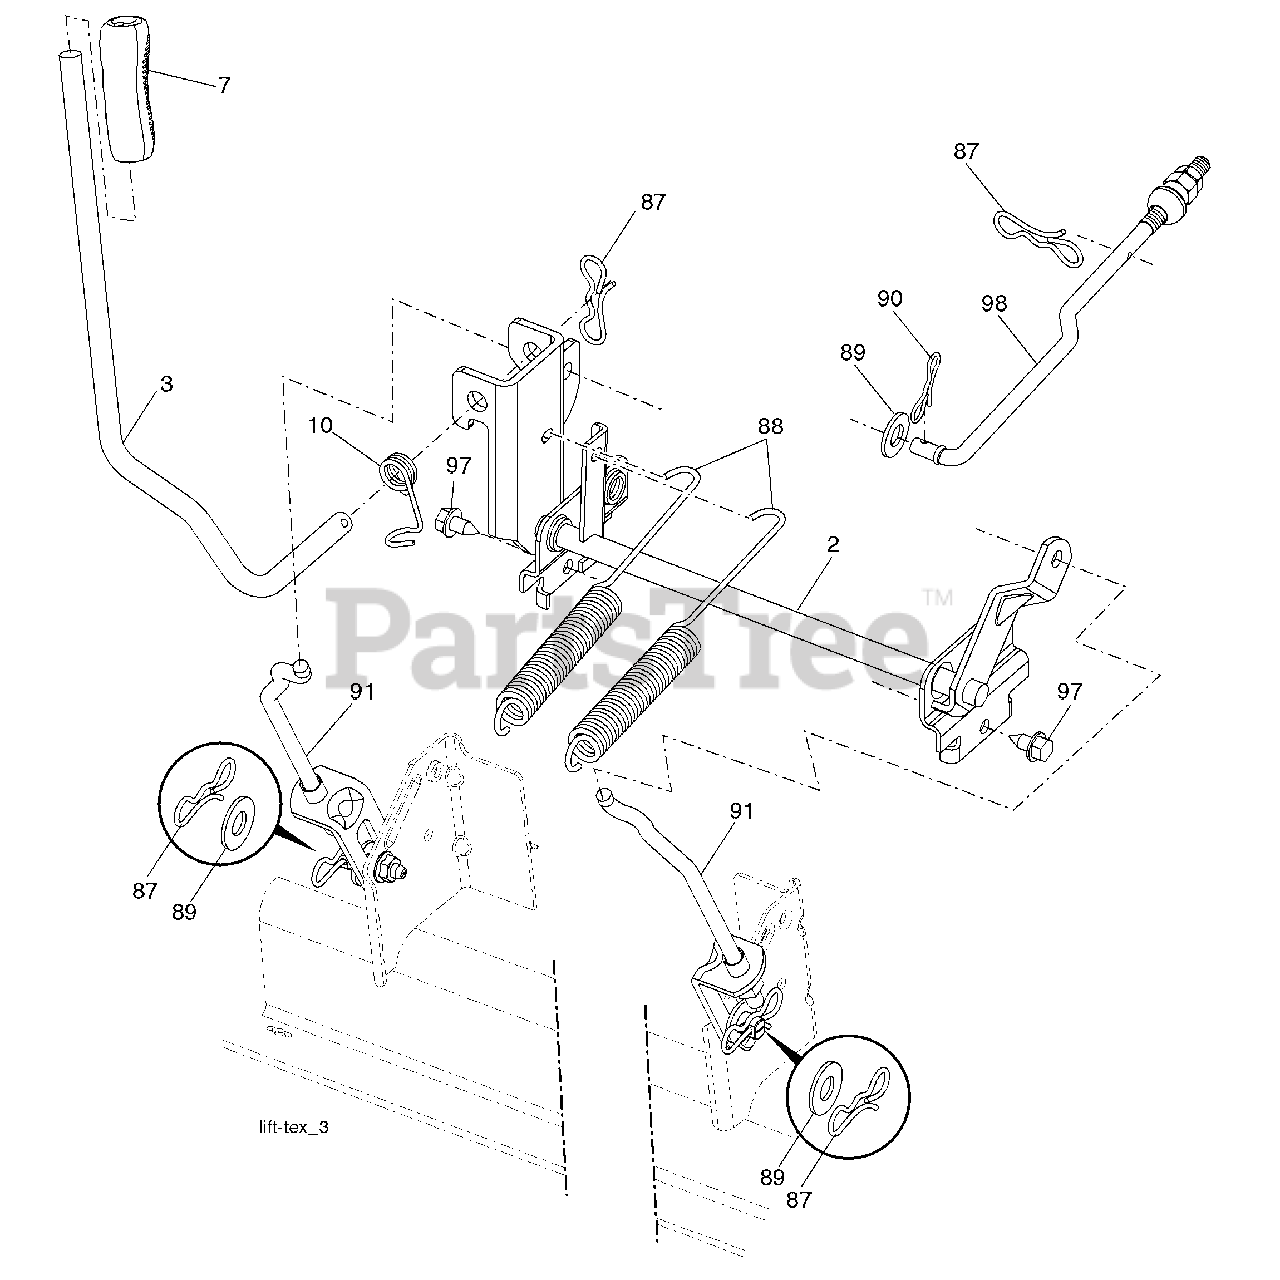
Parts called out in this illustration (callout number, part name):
2	Shaft Asm., Lift
3	Lever Asm., Lift RH
7	Grip, Lever
10	Spring Torsion
87	Pin Cotter 7/16 Bow Tie Lock
88	Spring Lift Assist
89	Washer Clear Zinc
90	Pin Cotter 5/16 Bow Tie Lock
91	Link Lift Susp Mower Rear
97	Screw 3/8-16 x .75
98	Link Lift Susp. Front Mower
